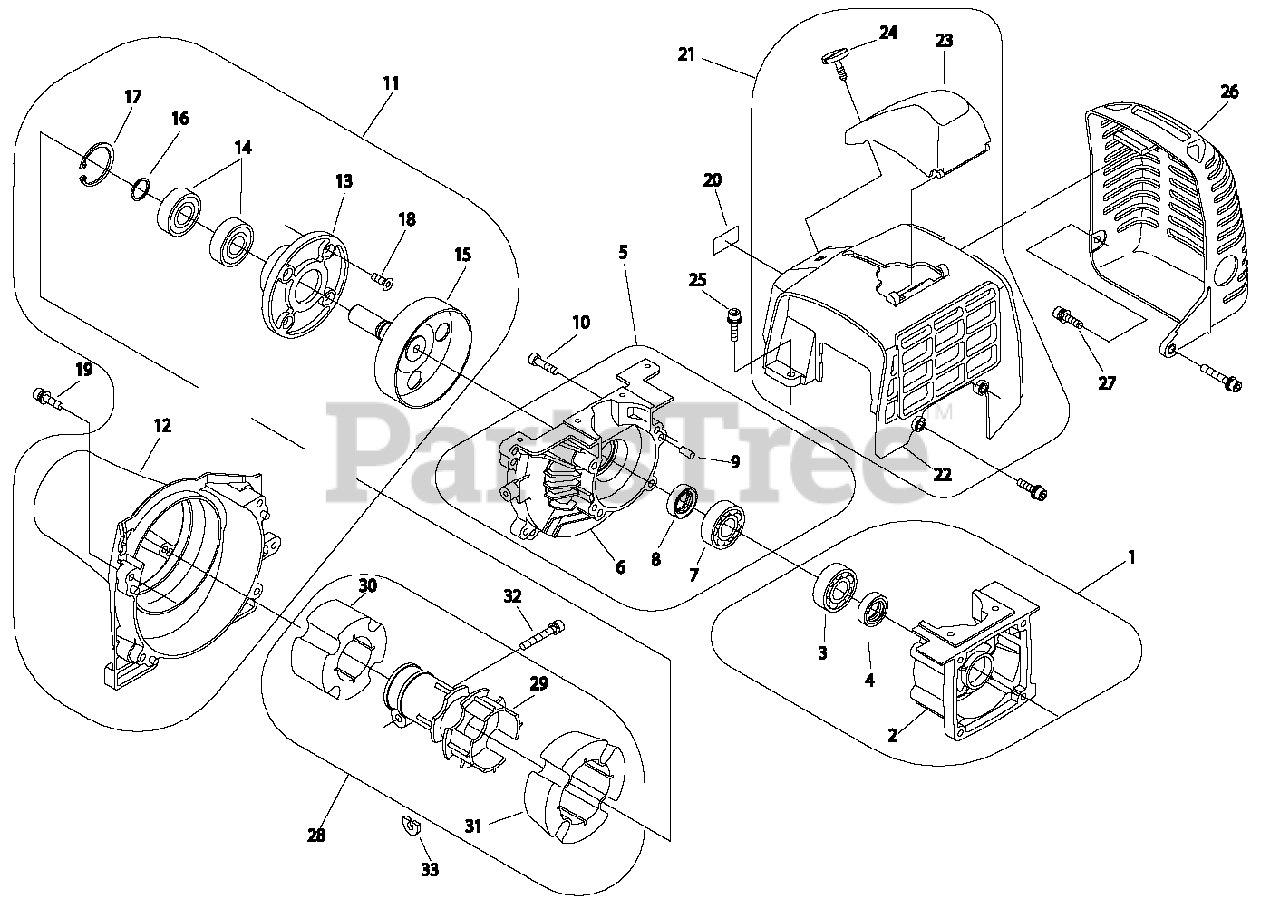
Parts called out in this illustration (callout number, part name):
1	CRANKCASE ASSY - REAR
2	CRANKCASE - REAR
3	BEARING, BALL - 6202
4	SEAL, OIL - 15
5	CRANKCASE ASSY - FRONT
6	CRANKCASE - FRONT
7	BEARING, BALL - 6202
8	SEAL, OIL - 15
9	PIN - LOCATING
10	SCREW - 5X30
11	FAN CASE ASSY
12	CASE, FAN
13	COVER, CLUTCH
14	BEARING, BALL - 6202
15	DRUM, CLUTCH
16	RING, RETAINING
17	RING, RETAINING - 35
18	SCREW
19	SCREW - 5X30
20	LABEL
21	ENGINE COVER KIT
22	COVER, ENGINE
23	COVER, SPARK PLUG
24	THUMBSCREW
25	SCREW - 5X16
26	COVER, EXHAUST
27	SCREW - 5X16
28	MAIN PIPE CLAMP KIT
29	JOINT
30	CUSHION - FRONT
31	CUSHION - REAR
32	SCREW - 6X28
33	SHIM
